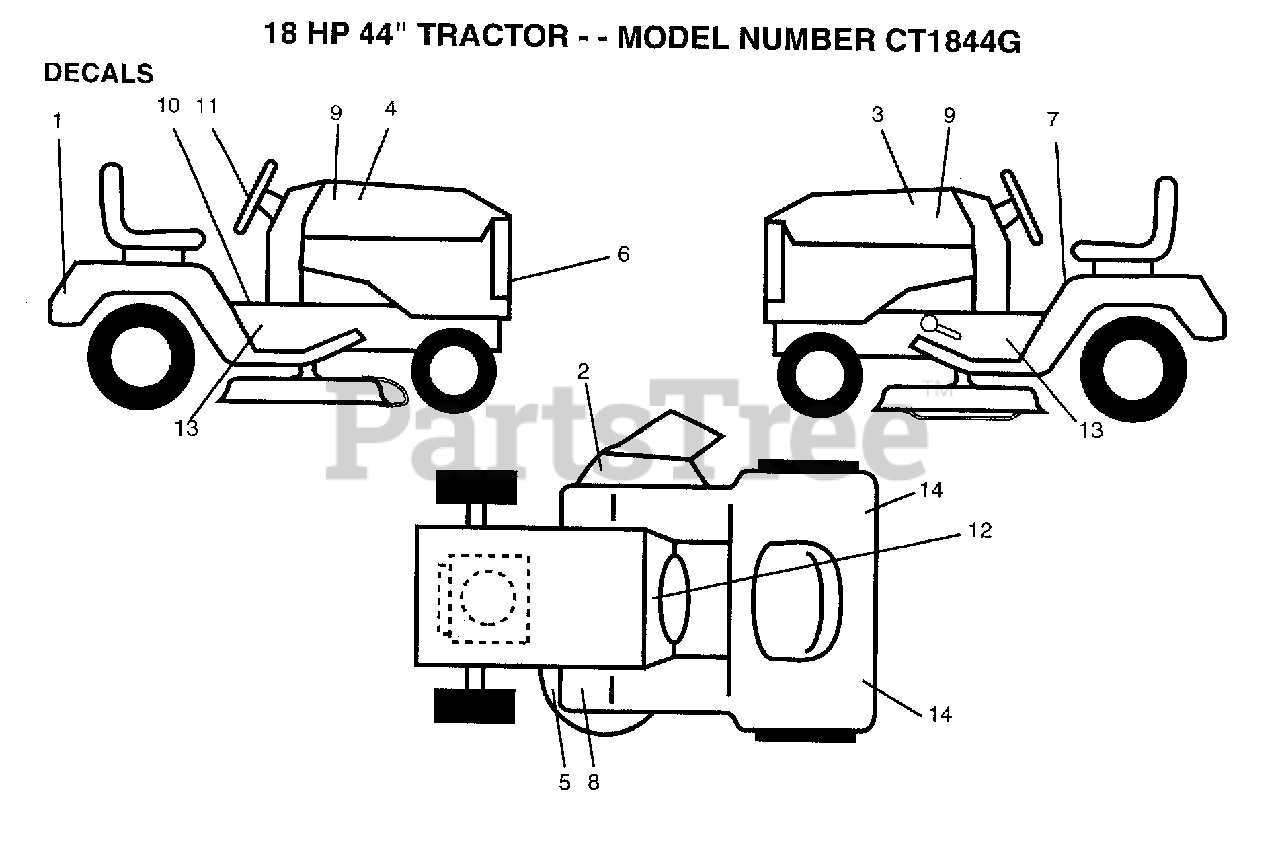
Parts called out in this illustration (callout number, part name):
1	DECAL.FENDER
2	"DECAL, WARNING"
3	DECAL.HOOD.LH.
4	DECAL.HOOD.RH.
5	"DECAL.V.BELT.44"""
6	DECAL.GRILLE
7	DECAL CAUTION
8	DECAL T
9	DECAL.HOOD.INSERT
10	DECAL BRAK PARK
11	DECAL INST STRWHL
12	DECAL.DASH.INSTR.
14	REFLECTOR-TAIL YT
